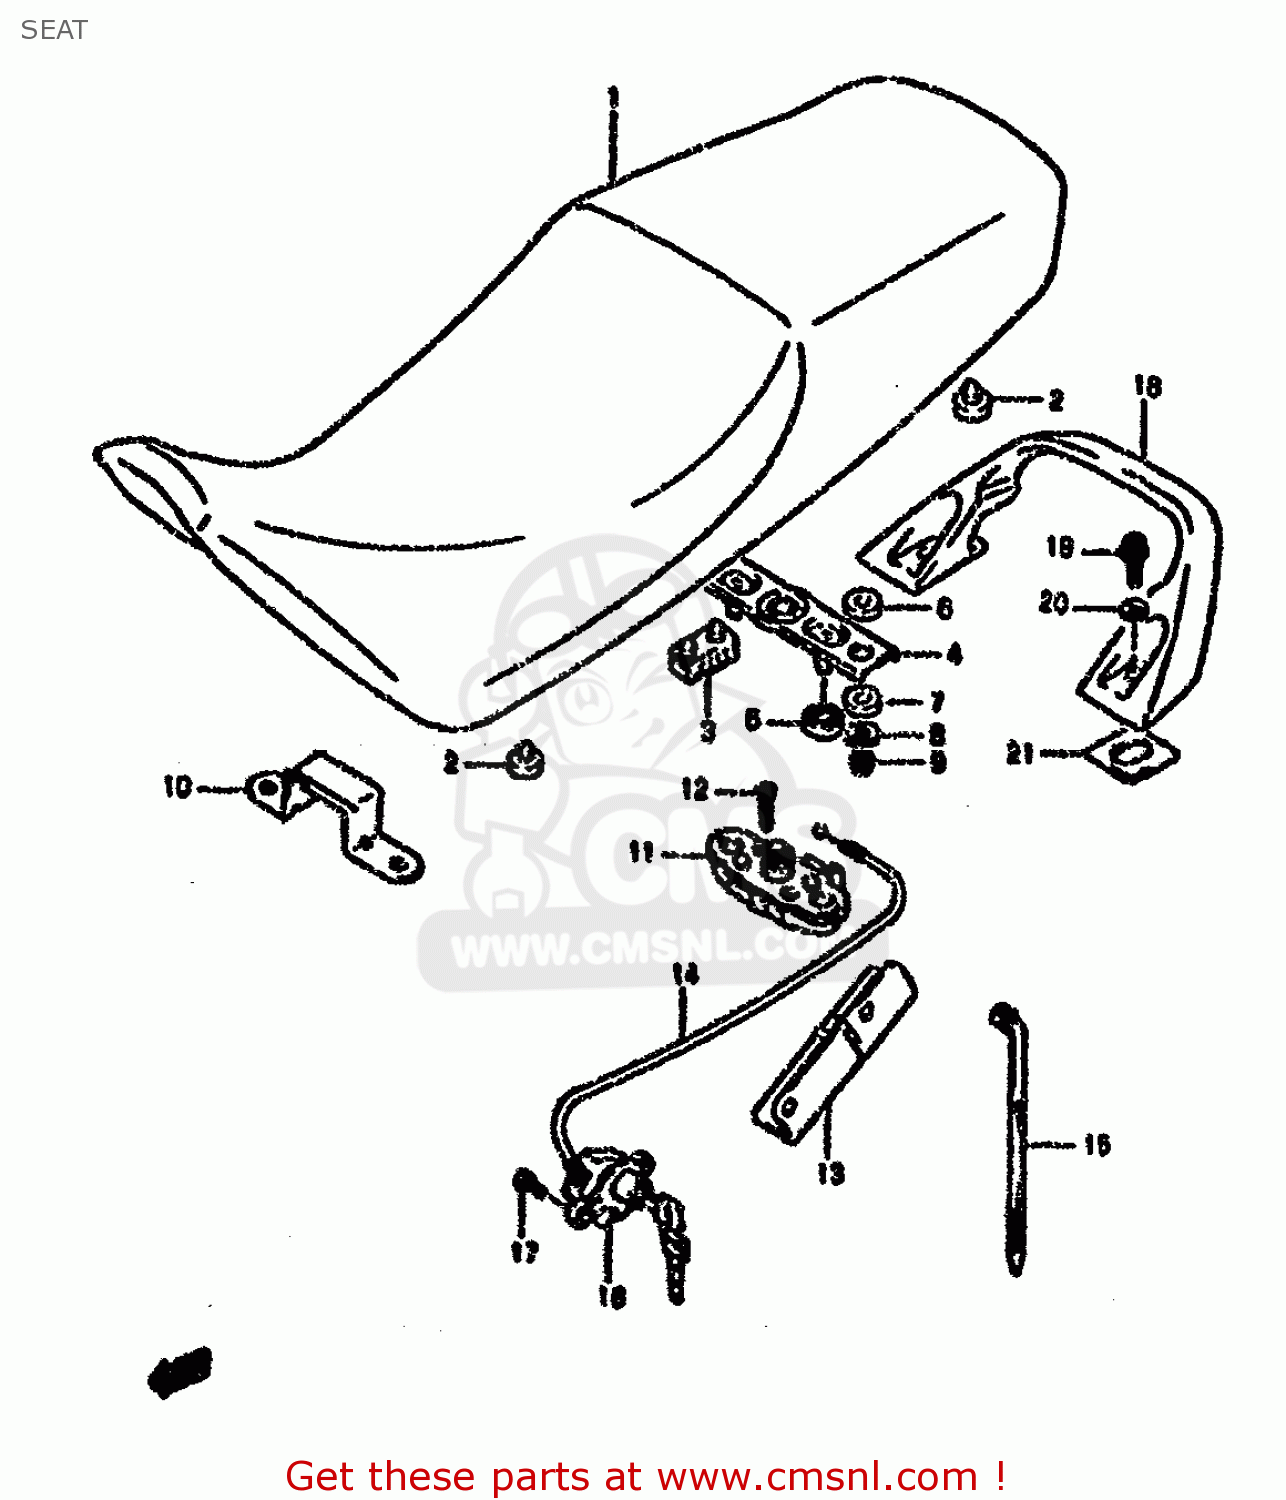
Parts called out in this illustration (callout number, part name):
1	SEAT SET
2	CUSHION
3	CUSHION,SEAT(40X20X15)
4	STRIKER,SEAT LOCK
5	CUSHION,SEAT LOCK(10X22X6)
6	CUSHION,UPR
7	CUSHION,LWR
8	WASHER
9	NUT
10	PLATE,SEAT FR HOOK
11	BRACKET,SEAT SUPPORT,RIGHT
12	SCREW
13	PLATE,SEAT LOCK CABLE
14	CABLE,SEAT LOCK
15	CLAMP L:165
16	LOCK SET,SEAT
17	BOLT
18	HANDLE,PILLION RIDER
19	BOLT
20	WASHER
21	CUSHION,FRAME COVER
